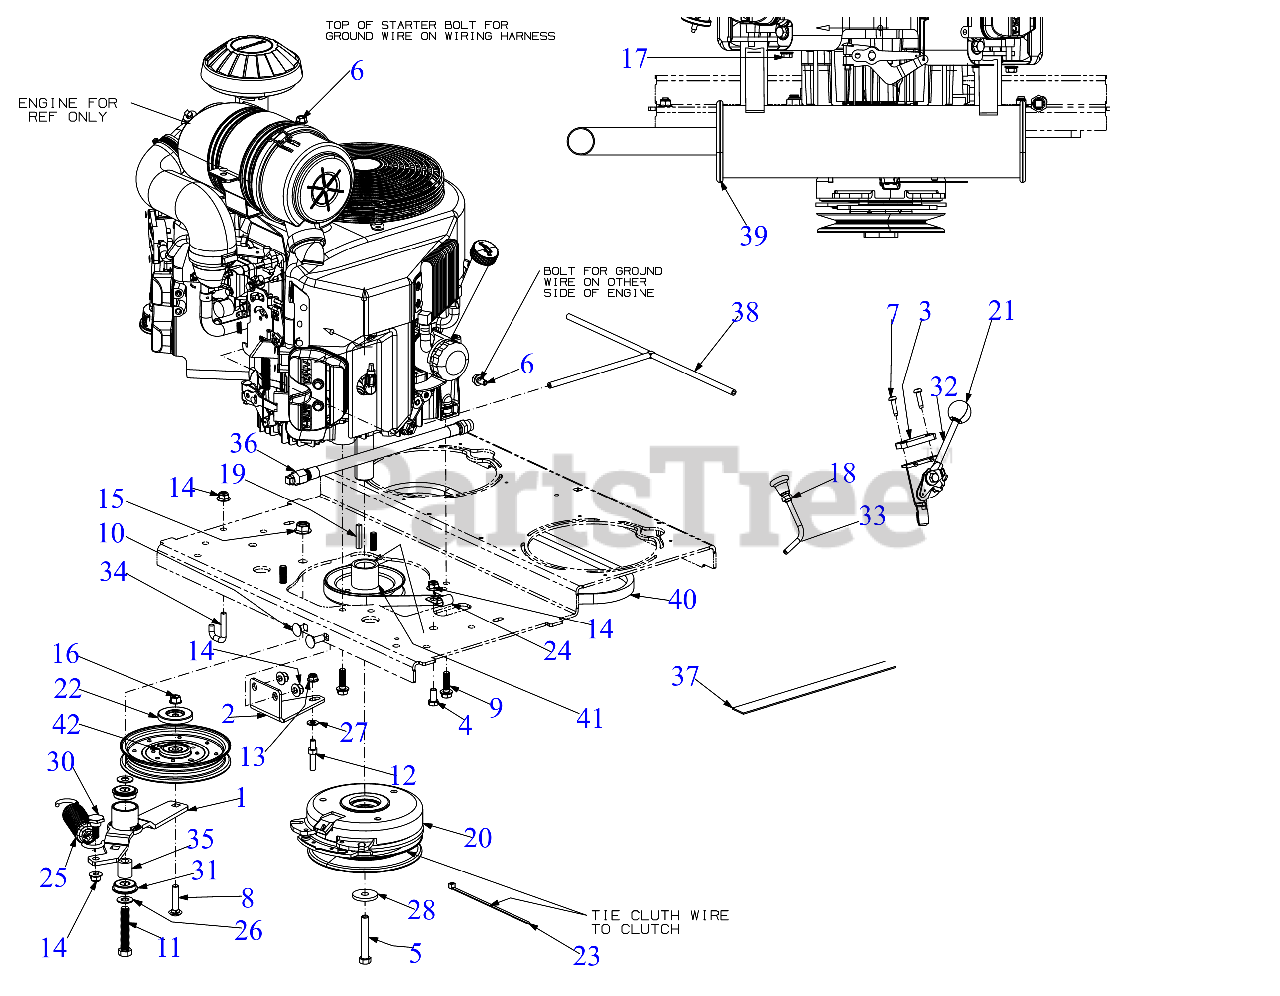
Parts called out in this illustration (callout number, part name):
1	TRANSMISSION IDLER BRACKET
4	HEX SCREW 3/8-16 x .75
5	SCREW 7/16-20:2.75 GR5
6	SCREW M8 x 1.25 x 16MM GR8.8
7	SCREW 1/4-20 x 1.0
8	CARRIAGE BOLT 3/8-16 x 1.75 GR5
9	SCREW 3/8-16 x 1.25 GR5
10	CARRIAGE BOLT 3/8-16 x 1.00 GR5
11	SCREW 1/2-13 x 2.75 GR5
13	FLANGE LOCK NUT 5/16-18
16	HEX LOCK NUT
17	HEX FLANGE NUT
18	HEX JAM NUT 3/8X24
19	SQUARE KEY 1/4 x 1.50
20	ELECTRIC PTO CLUTCH
20	CLUTCH HARNESS 11.625
22	PULLEY CAP
23	7" CABLE TIE
24	J TYPE CLIP
25	EXTENSION SPRING W/HOOK
26	FLAT WASHER .510X.995
27	FLAT WASHER
28	FLAT WASHER .45 x 1.5 x .172 HT
30	SHOULDER SCREW .625 x .302 x 3/8-16
31	ROLLER BEARING .5X1.37X.44
32	THROTTLE CABLE 59"
33	CHOKE CABLE
34	ROD SPRING HOOK
35	SPACER 0.51 x 0.88 x 1.00
36	OIL DRAIN HOSE
37	HEAT SHIELD 24"
38	ROLLOVER VENT HOSE ASSEMBLY
39	MUFFLER - KAWASAKI 1000
40	BELT 61.5"
41	PULLEY - PUMP DRIVE
42	IDLER PULLEY
